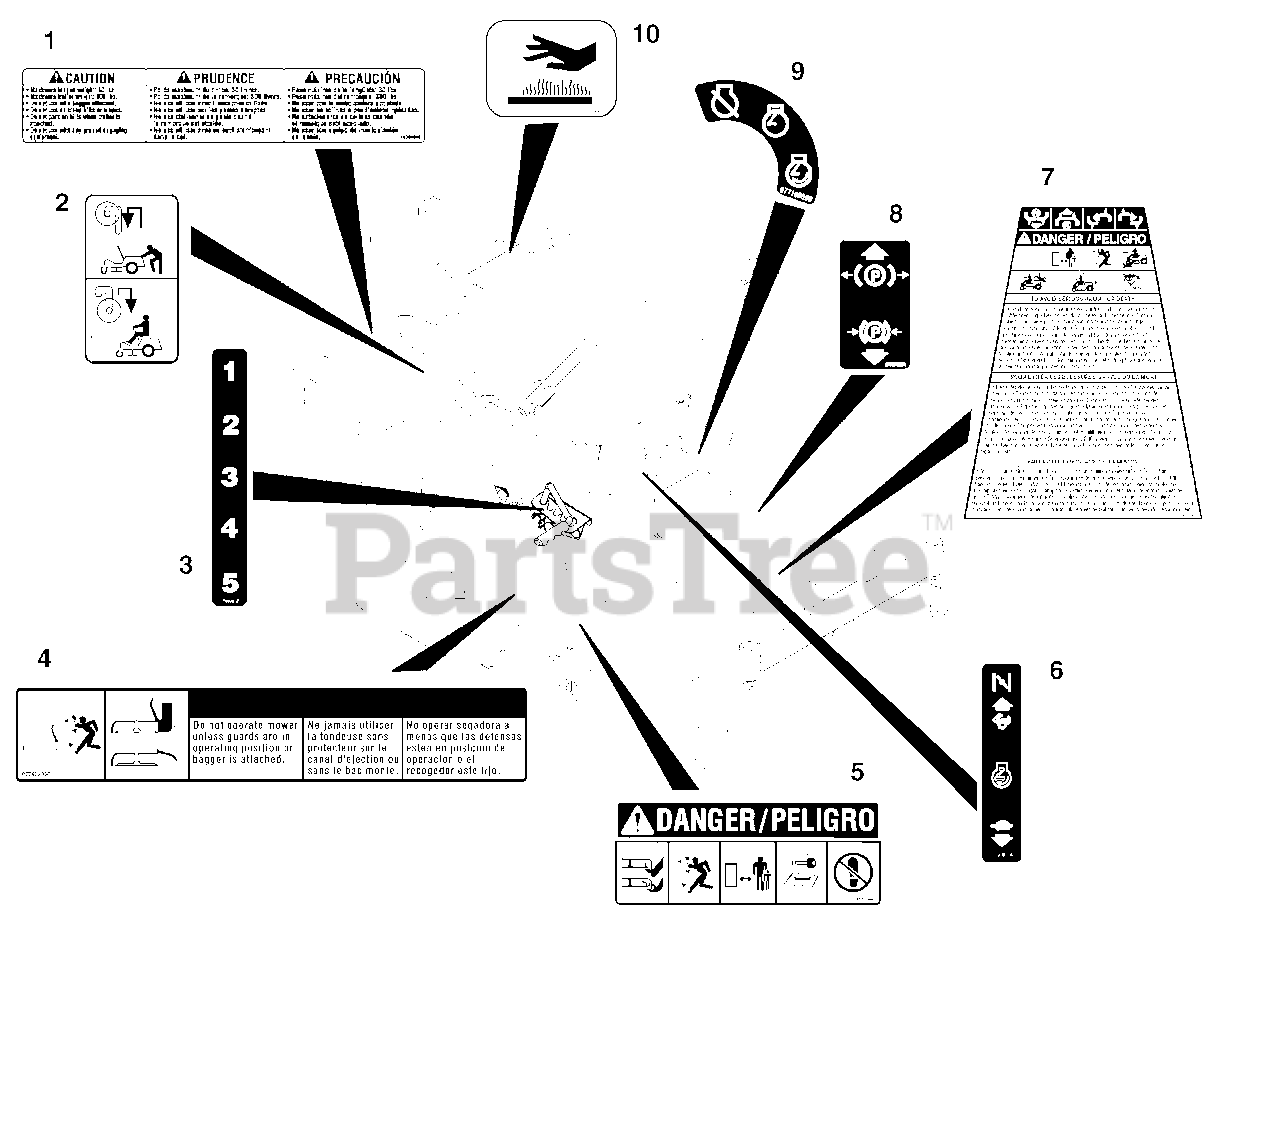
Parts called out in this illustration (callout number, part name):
1	DECAL, TRAILER HITCH
2	DECAL, TRANSMISSION DISCONNECT
3	DECAL-DECK LIFT
4	DECAL, WARNING
5	DECAL, MOWER PAN DANGER
6	DECAL-THROTTLE RER/SPORT
7	DECAL-EZR WARNING
8	DECAL, PARKING BRAKE LEVER
9	DECAL - IGNITION
10	DECAL, HOT SURFACE
